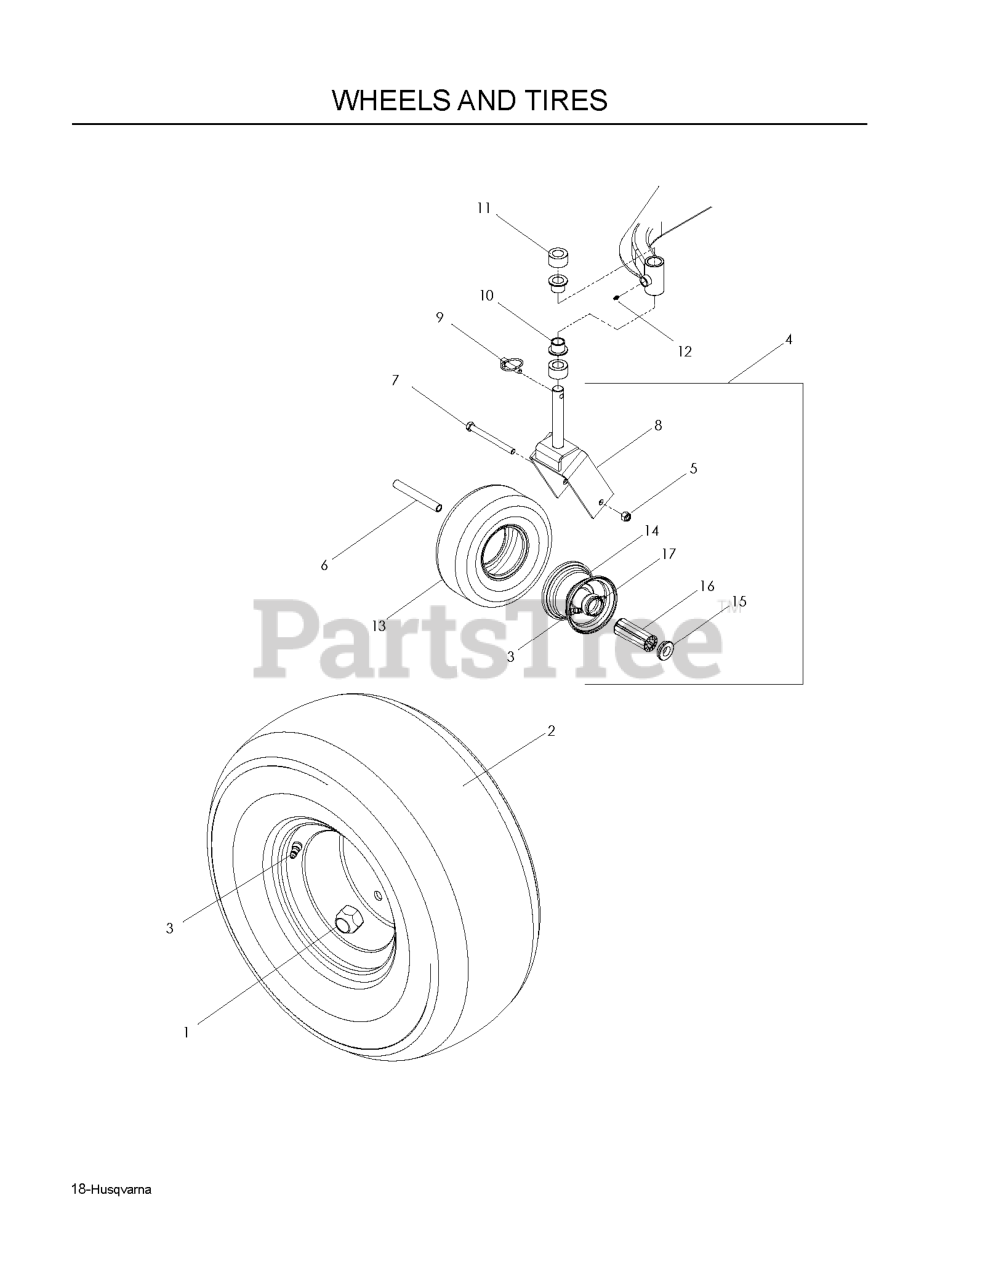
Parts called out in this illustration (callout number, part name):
1	LUG NUT 1/2F
2	TIRE/WHEEL ASSY
3	VALVE STEM TR-412
4	TIRE/WHEEL.CASTER
5	NUT 1/2-13 HEX NYLOC ZD
7	HCS 1/2C X 5 1/2
8	CASTOR FORK
9	LYNCH PIN 7/16
10	BSHG 1.003X1.252X1.75 LG OIL
11	CASTER SPACERS - 1"
12	ZERK
13	TIRE - CASTER
15	BEARING RETAINER
16	ROLLER BEARING-CAGED 3 1/4'
17	ZERK
